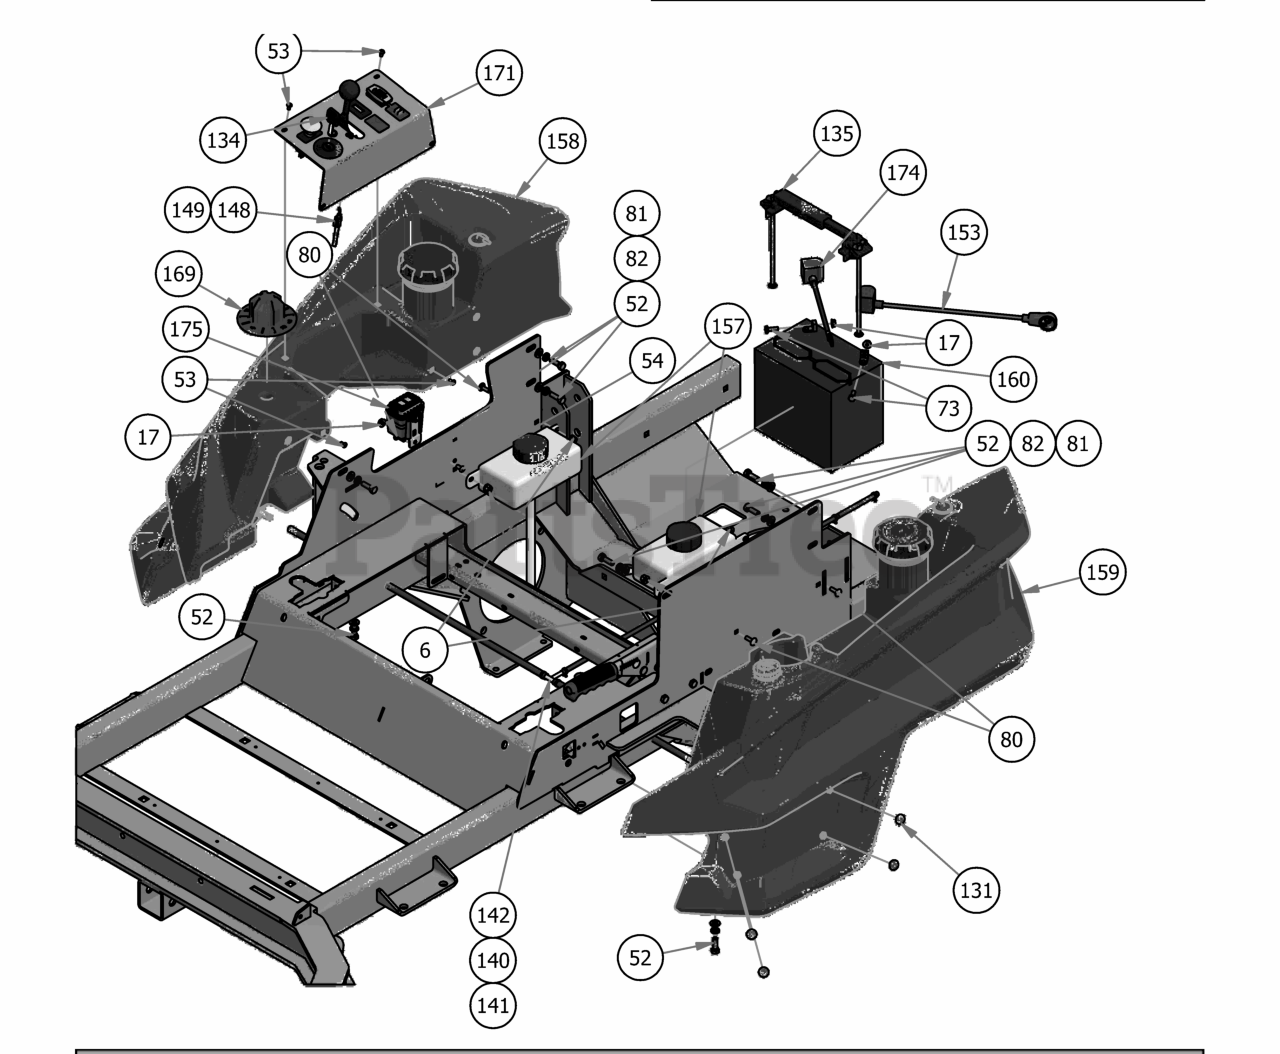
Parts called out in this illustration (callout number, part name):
6	1/4-20 Nylon Insert flange Nut
11	3/8" Fine Threaded Jam Nut
15	5/16" Nylon Flange Nut
17	1/4-20 Hex Flange Nuts Zinc w/Serrations
52	5/16" x 1" Bolt
53	10-32 x 3/8" Button Socket Head Bolt
54	1/4" x 1/2" BS C/S 18-8 SS
70	5/16" x 2 1/2" Bolt
73	1/4" x 3/4" Hex Bolt
80	1/4" x 3/4" Carriage Bolt
81	5/16" Flat Washer
82	5/16" Lock Washer
91	2019 Outlaw Brake Handle Spacer .625 x 1.5
131	3/16 x .48 Christmas Tree Nylon Black
134	Ignition Key
135	Hold Down Assembly
140	2019 Rebel Rogue Renegade Fuel Line for Vanguard & Yamaha
141	2019 Rebel Rogue Renegade Fuel Line for Kohler
142	2019 Rebel Rogue Renegade Fuel Line for Kawasaki
147	Choke for 36Hp Vanguard & FX1000 Kawasaki
148	Outlaw Throttle Cable
149	Throttle Cable for 36Hp Vanguard & FX1000 Kawasaki
153	14" Red Battery Cable-Base Outlaw
154	Long Brake Cable
157	2019 Rebel Hydro Tank Assembly
158	2019 Right Rebel, Rogue, Renagade Fuel Tank (GAS)
159	2019 Left Rebel, Rogue, Renegade Fuel Tank (GAS)
161	2019 Brake Handle Assembly
165	2019 Rigid Frame
169	2019 Rigid Deck Dial 1.5 to 5.5
171	Rebel/Rogue Control Panel Assy
174	Starter Cable
175	2019 Wiring Harness-Rebel/Rogue
